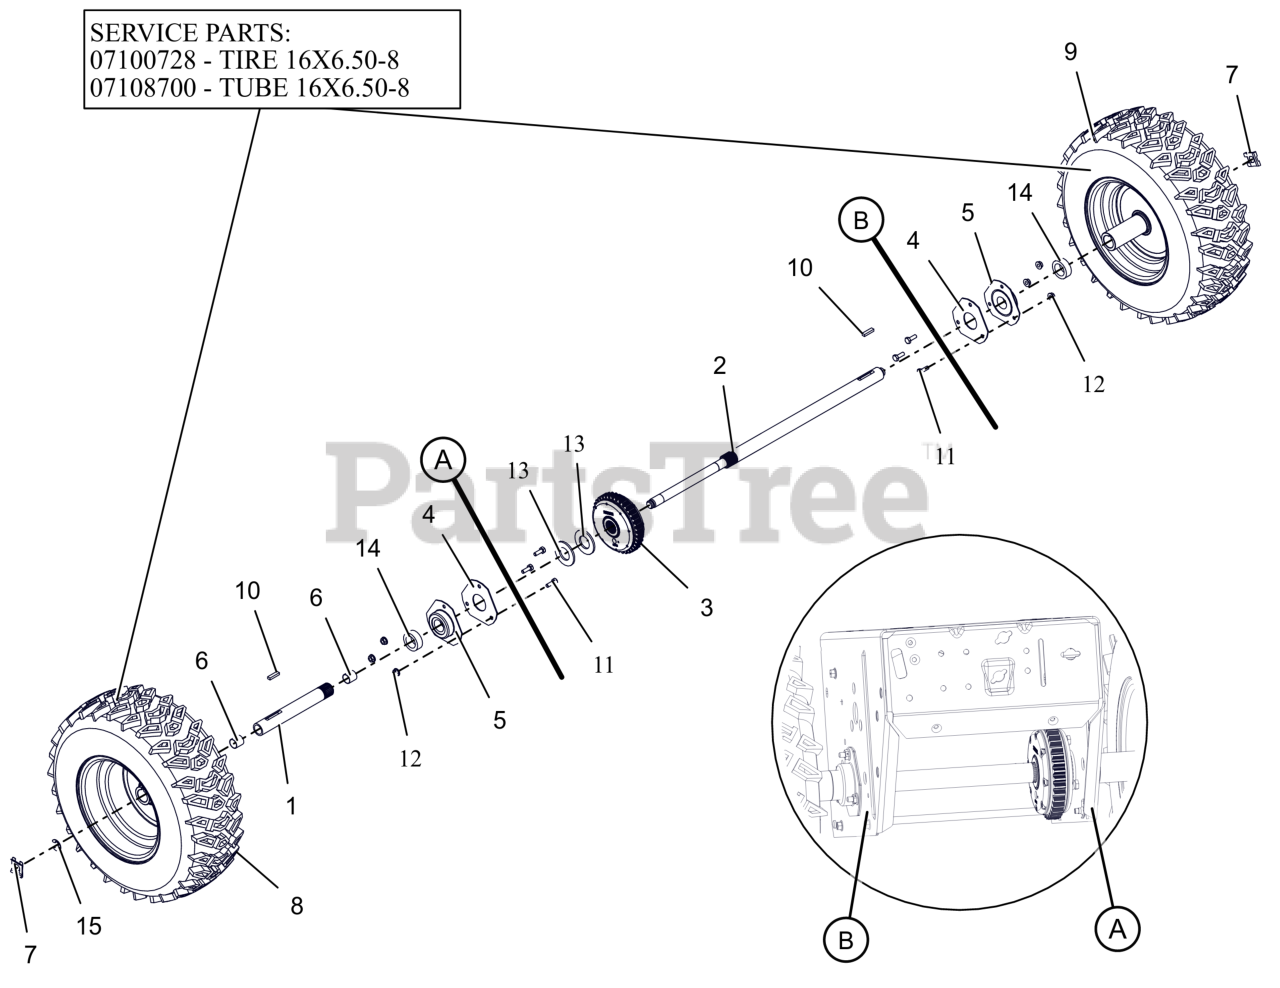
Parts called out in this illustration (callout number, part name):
1	AXLE, SHORT-AUTO W/BUSHINGS
2	AXLE, LONG-PRO AUTO DIFF
3	DIFFERENTIAL, AUTOMATIC
4	PLATE, BEARING SPACER
5	BRG-FLG 1.003/1.000 3 BOLT
6	BSHG-SLV .706X.764X.75 BRZ
7	CLIP, SNAP .625 DIA
8	TIRE/WHEEL,RH 16X6.5-8 DIFF T2
9	TIRE/WHEEL,LH 16X6.5-8 DIFF T2
9	SNOW TIRE, 16/6.50-8 K478 DIRECTIONAL
9	TIRE TUBE 16X6.50/7.50-8 4 PLY TR13 STRIGHT VALVE
10	KEY-RECT .25X.188X1.00
11	BLT, HEX .25-20X.75 G5 ZCC
12	NUT-LK-CTR-FLG .25-20 ZC120
13	WSHR, FLT 1.062X2.000X.134 ZCC
14	SPACER, PRO AXLE BEARING
15	RG-RTNG-EXT .625X.042
